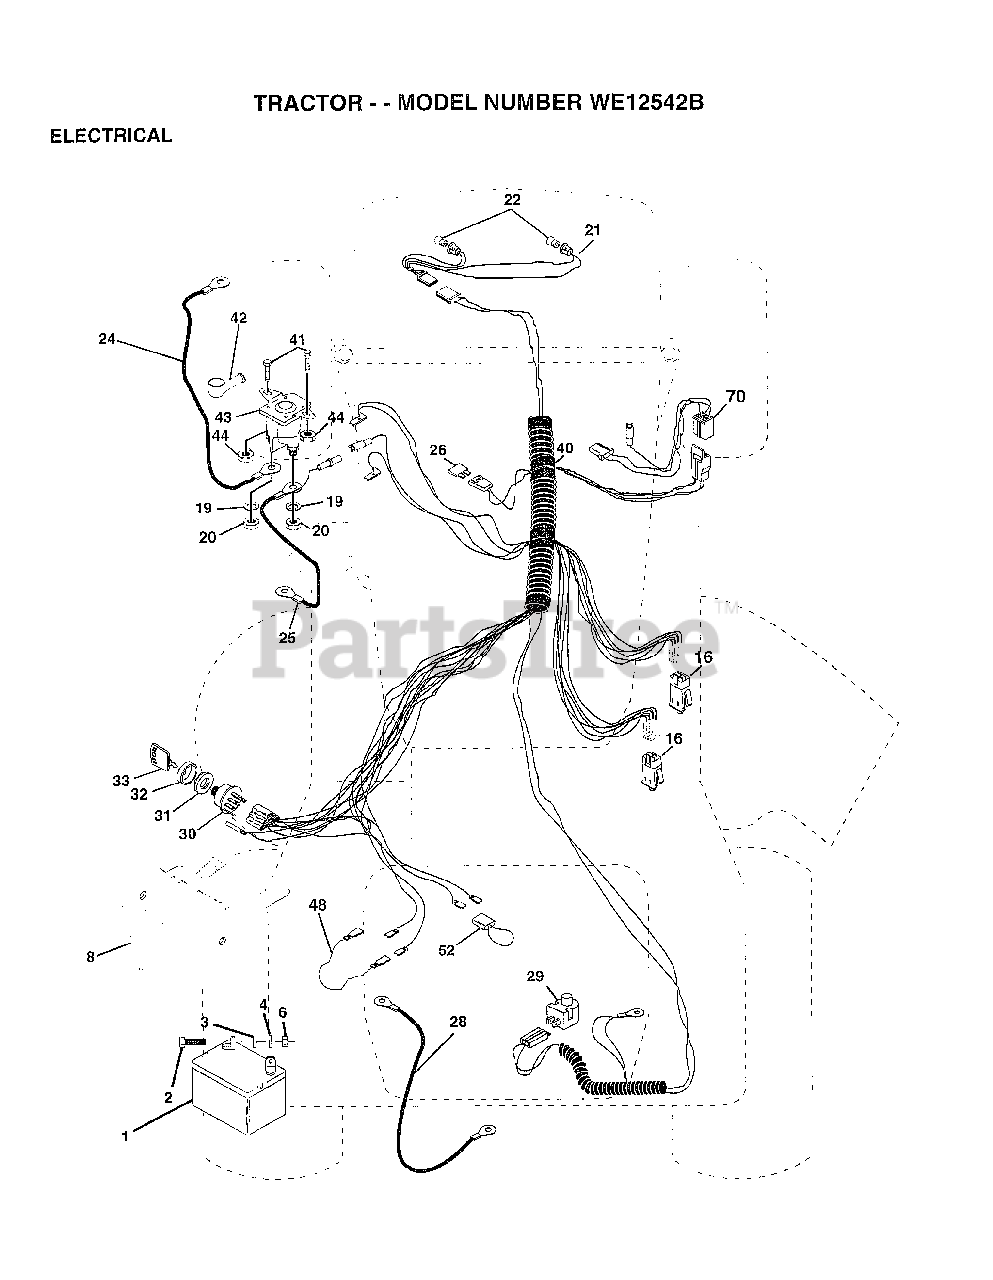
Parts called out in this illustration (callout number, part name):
2	BOLT LT
3	WASHER
4	LOCKWASHER
8	"CASE,BATTERY.MECH"
16	SWITCH INTERLOCK
20	NUT
21	"HARNESS,LIGHT SOC"
22	HEADLAMP BULB
24	"CABLE T, BATTERY"
25	CABLE.BTRY.6GA.RD
26	FUSE HYT
28	CABLE T
29	SWITCH SEAT
30	SWITCH IGN 4POS
31	NUT IGNITION
32	COVER KEY SWITCH
33	KEY
40	HARNESS-IGNITION
41	BOLT HXHD FIN
44	NUT HXKEP 1/4X20
48	ADAPTER AMMETER
52	PROTECTION LOOP
70	HARNESS ENG DUAL
